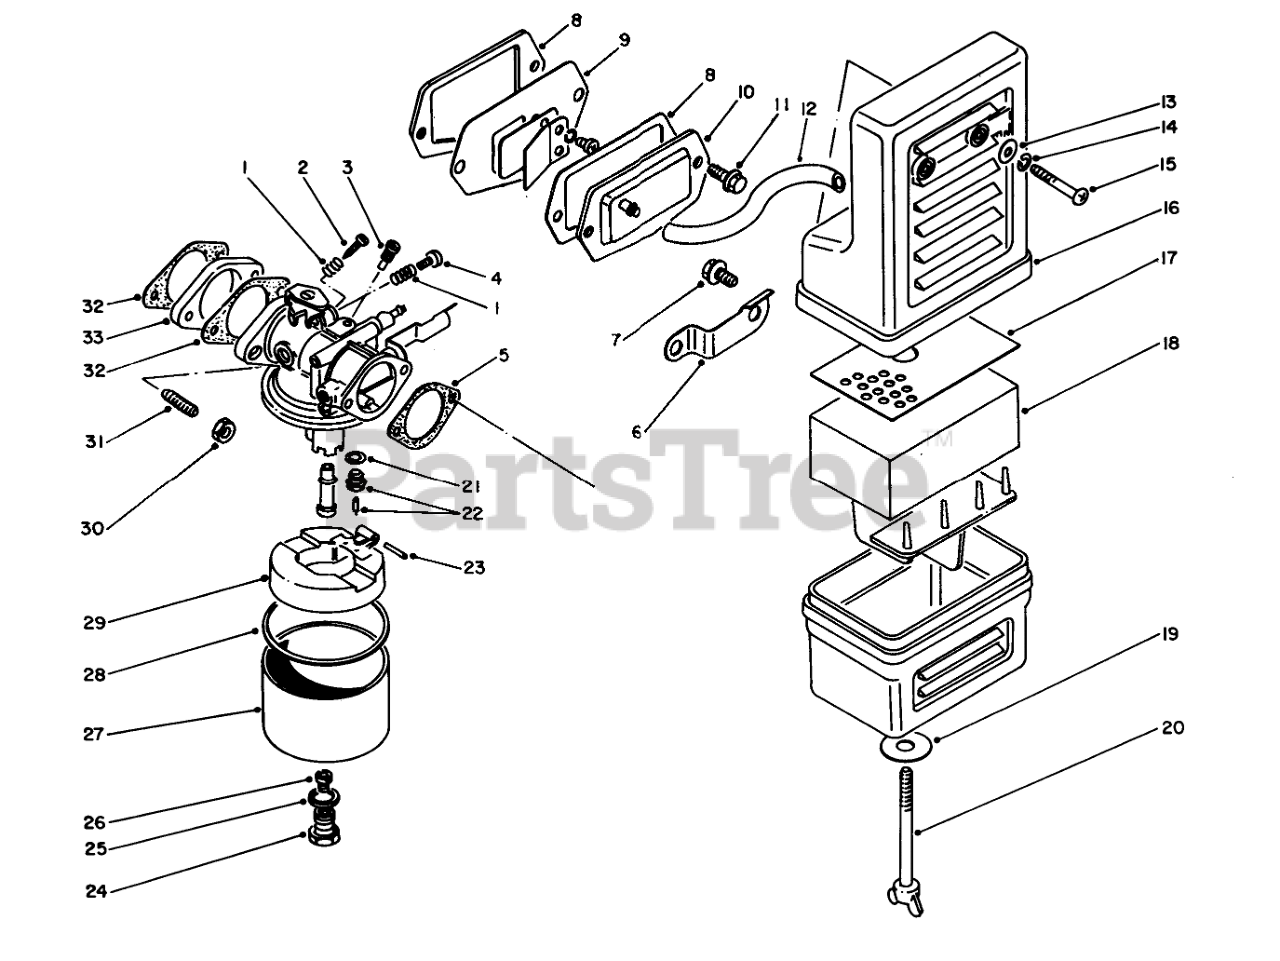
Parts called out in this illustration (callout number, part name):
1	SPRING-PILOT SCREW
2	ADJUSTER
3	Jet-Pilot (47.5)
4	SCREW
5	AIR CLEANER GASKET
6	Bracket
8	GASKET
9	Reed Valve Assembly
13	WASHER
14	Washer
15	SCREW
16	Cleaner Assembly-Air (Incl. Ref. #17-20)
17	Holder
18	FILTER
19	WASHER
20	Bolt-Wing
21	GASKET
22	NEEDLE VALVE
25	GASKET
26	MAIN JET
27	Carburetor Assembly (Incl. Ref. #1-4, 21-26 & 28-29)
28	GASKET
29	FLOAT
31	Bolt-Stud
32	Gasket
33	INSULATOR
